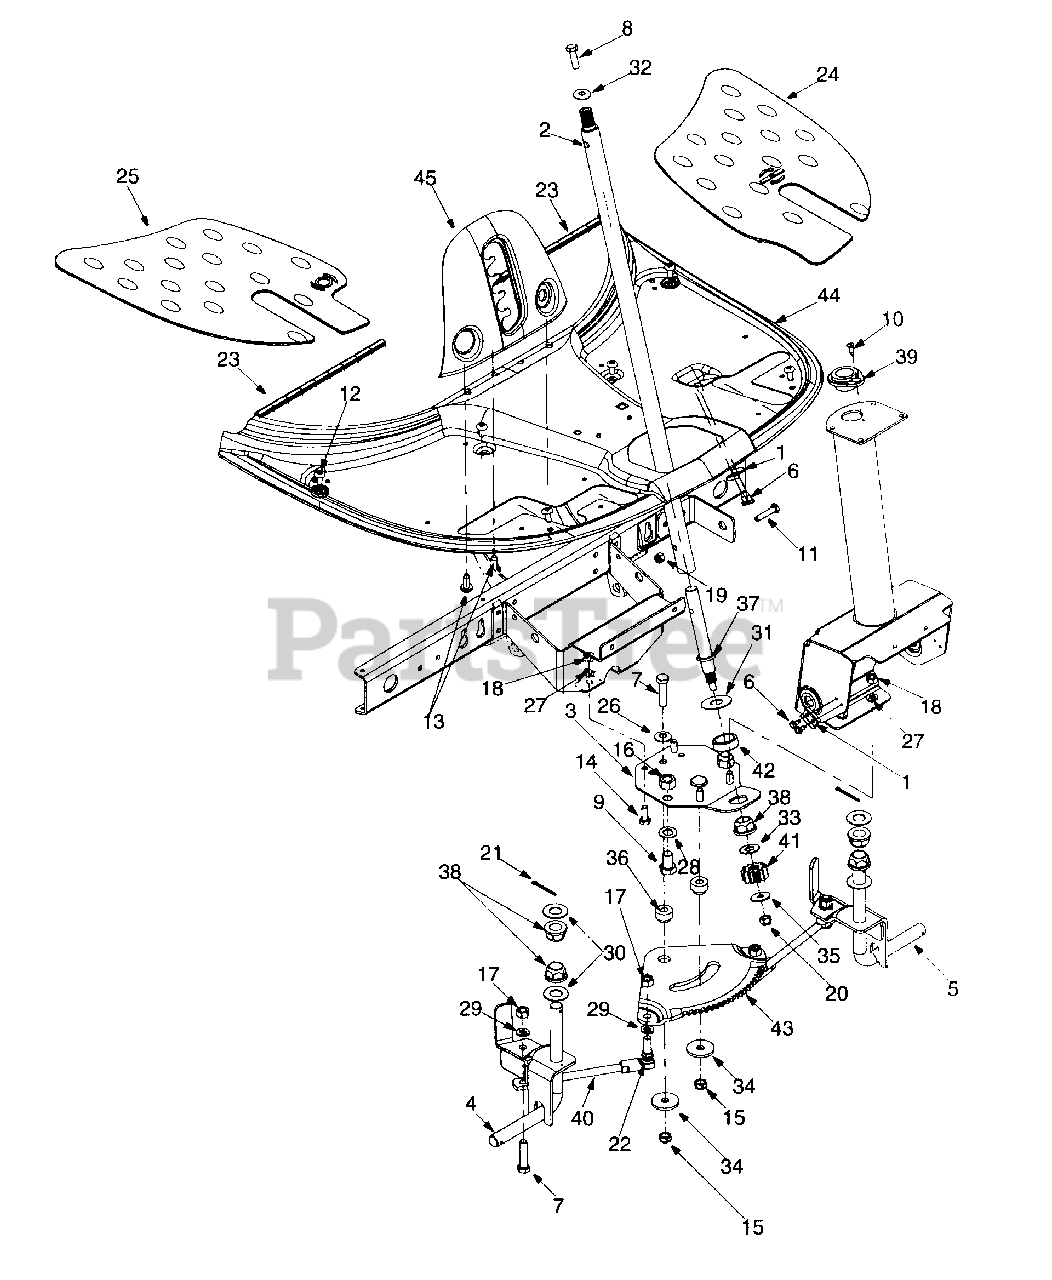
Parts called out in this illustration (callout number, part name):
1	Switch Plate
2	Steering Tube Assembly
3	Steering Support Bracket
4	Front Axle Assembly: RH
5	Front Axle Assembly: LH
6	Hex Screw AB
7	Hex Screw 3/8-24 x 1.5" Gr.5 Special
8	Lock Screw 5/16-18 x 1.0" Gr.5
9	Hex Screw 1/2-13 x 0.75"
10	Oval Csunk Screw #10-16 x 0.625"
11	Hex Screw 1/4-20 x 1.25 Gr.5 Special
12	AB Screw 1/4-14 x 0.625"
13	Self-Tapping Screw 5/16-18 x 0.75"
14	Hex Screw 5/16-18 x 0.75"
15	Lock Nut 3/8-24
16	Hex Nut 1/2-13
18	Hex Nut
19	Lock Nut 1/4-20
21	Cotter Pin
22	Ball Joint
23	Trim Strip
24	Floor Pad: LH
25	Floor Pad: RH
26	Bell Washer
27	Lock Washer
28	Flat Washer
29	Lock Washer
30	Flat Washer
31	Flat Washer
32	Belleville Washer
33	Flat Washer
34	Flat Washer
35	Flat Washer
37	Steering Adapter
38	Hex Flange Bearing
39	Bearing: Steering Column
41	Pinion Gear
42	Spacer
43	Gear: Steering Segment
